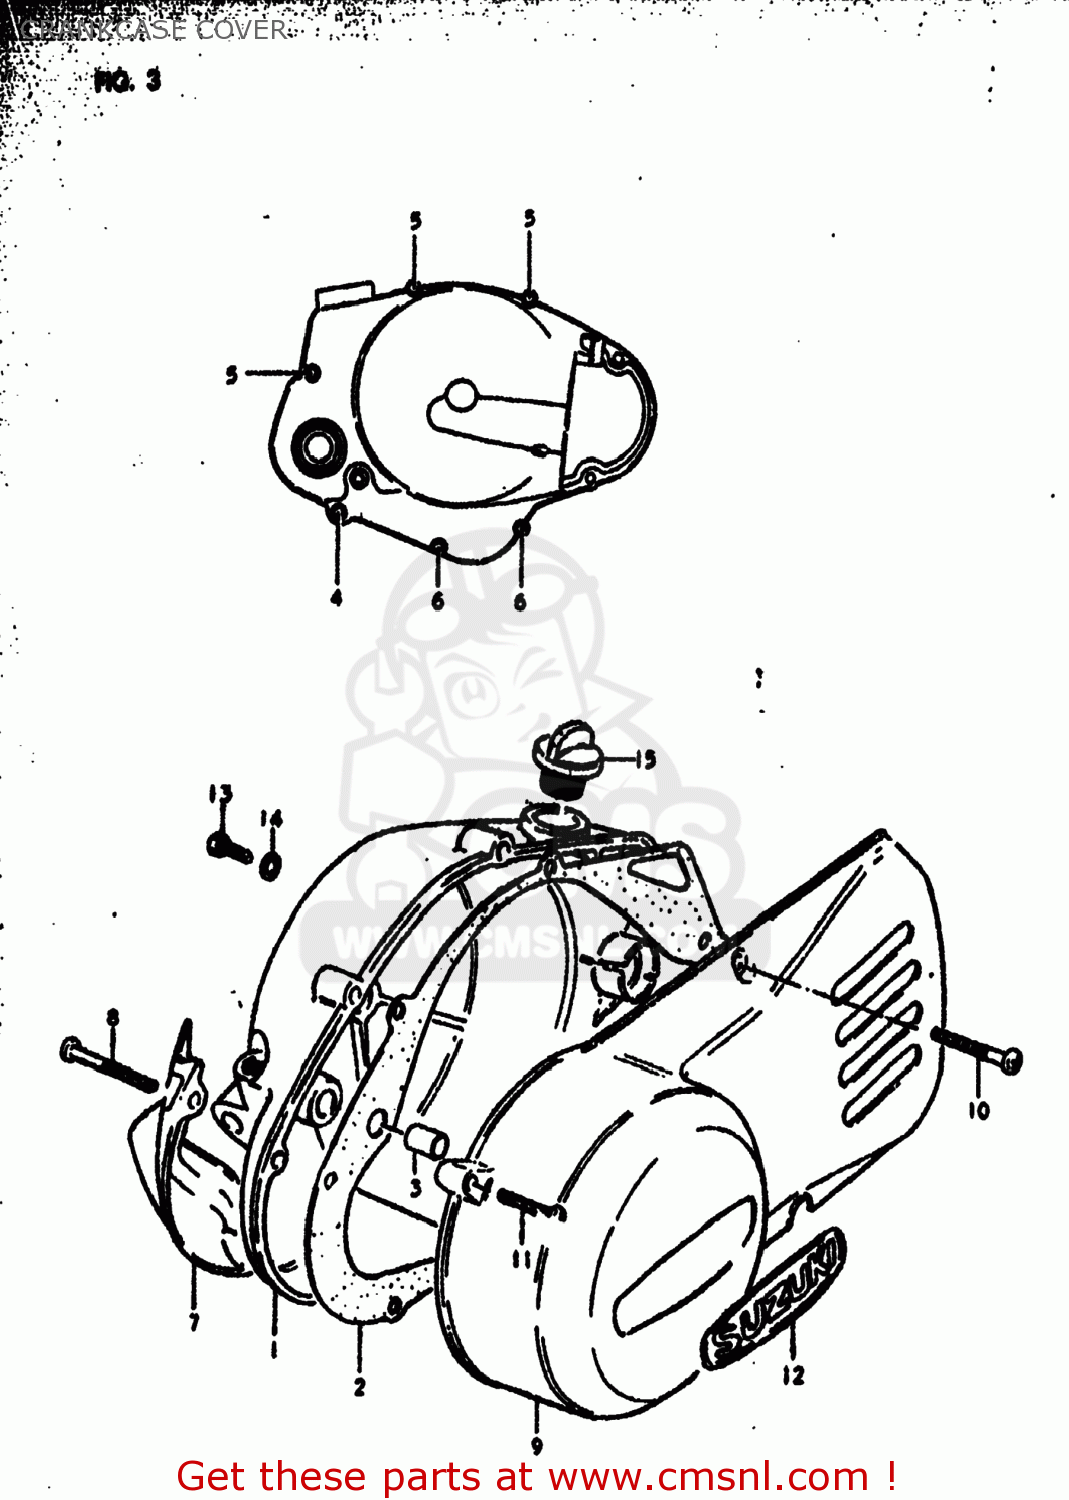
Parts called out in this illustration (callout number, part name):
1	COVER,CLUTCH
2	GASKET,CLUTCH COVER (MCA)
3	PIN
4	SCREW (6X45)
5	SCREW
6	SCREW
7	COVER,CLUTCH RELEASE A
8	SCREW
9	COVER,MAGNETO
10	SCREW 6X30
11	SCREW
12	EMBLEM,MAGNETO COVER
13	SCREW(6X10)
14	GASKET(6.2X11X1) (NAS)
15	PLUG
